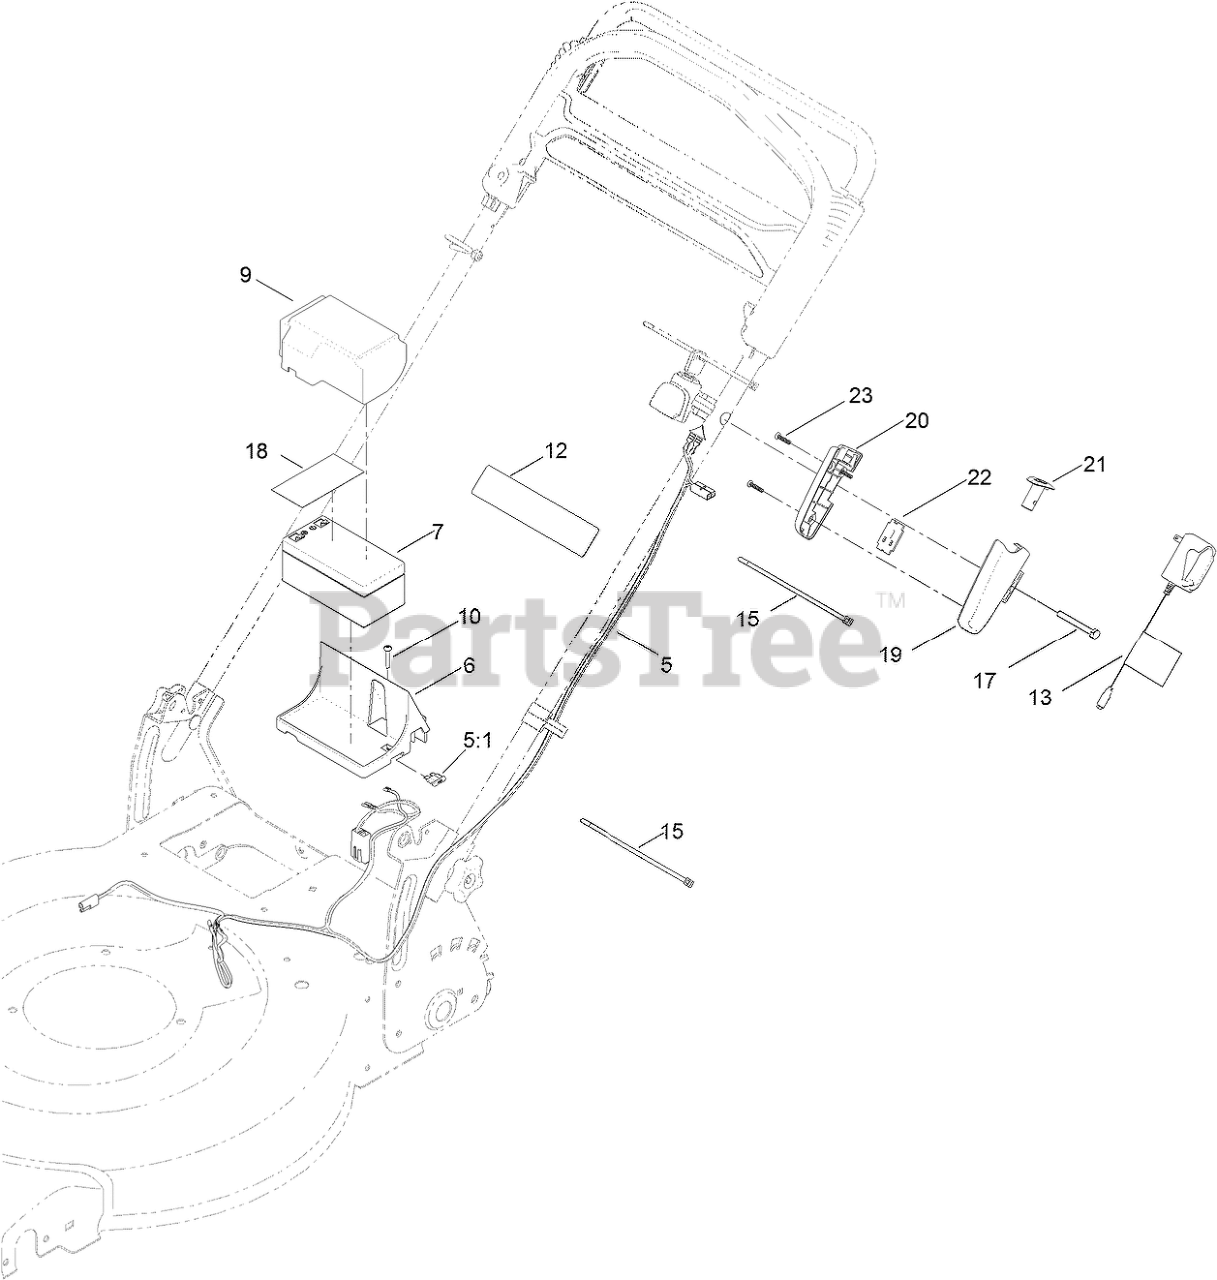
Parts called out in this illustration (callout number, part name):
5	HARNESS-WIRE
5:1	FUSE-40 AMP
6	TRAY-BATTERY
7	BATTERY-WET
9	COVER-BATTERY
10	SCREW-PPH, PLASTITE
12	DECAL-WARNING
13	CHARGER-BATTERY
15	TIE-CABLE
17	SCREW-HH
18	DECAL-TERMINAL, BATTERY
19	HOUSING-SWITCH, LH
20	HOUSING-SWITCH, RH
21	BUTTON-SWITCH
22	SWITCH-PUSH BUTTON
23	SCREW-PPH
